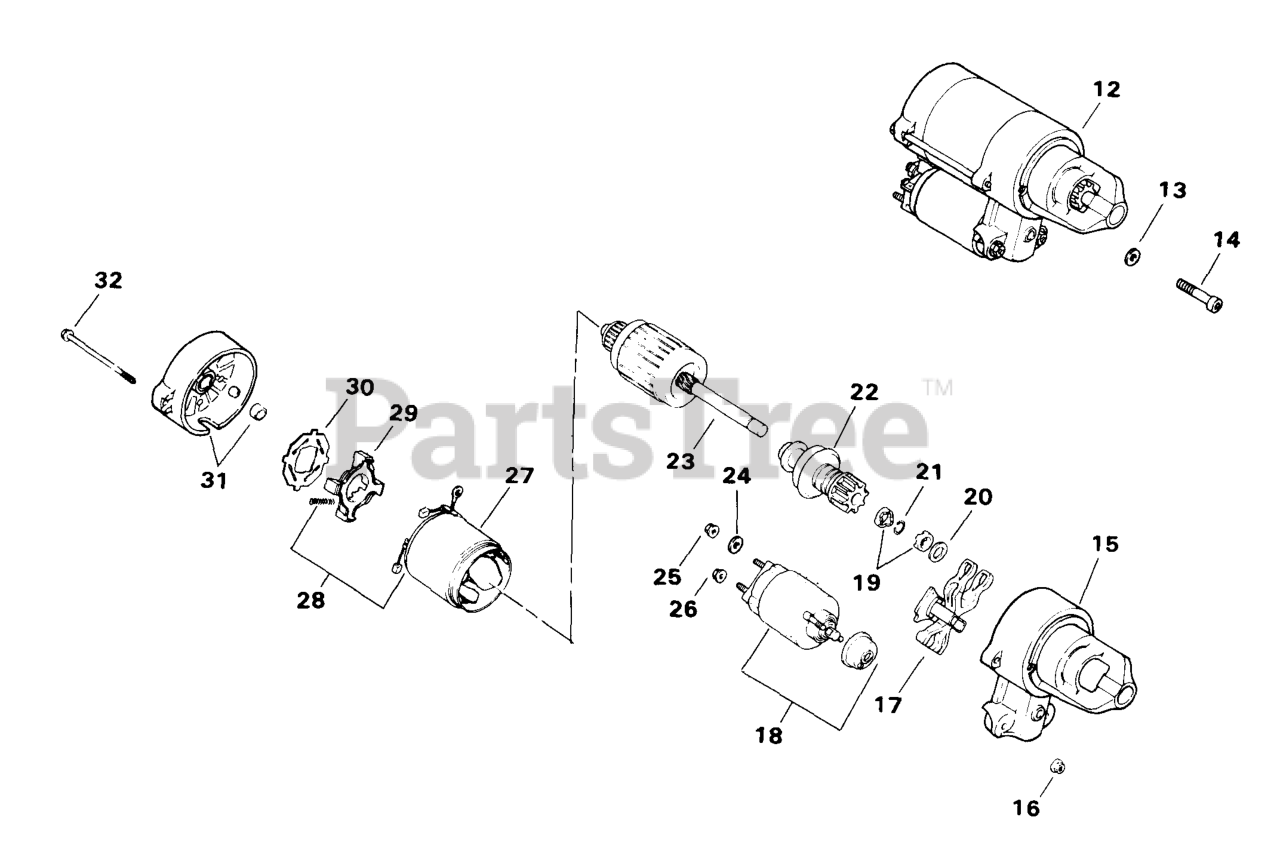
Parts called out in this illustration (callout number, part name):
12	ELEC STARTER-SOLENOID SHIFT-(#DSC)
13	WASHER, FLAT 1/4" (O.D. 1/2")
14	SCREW - (#DSC)
15	CAP, DRIVE END - DISCONTINUED
17	DRIVE LEVER
19	KIT - USE 24 755 84
20	KIT - USE 24 755 84
21	KIT - USE 24 755 84
22	DRIVE - (#DSC)
23	ARMATURE-DISCONTINUED
24	WASHER - DISCONTINUED
25	NUT - DISCONTINUED
28	BRUSH & SPRING KIT
29	BRUSH HOLDER
30	INSULATOR
31	CAP, COMMUTATOR END
32	THRU BOLT
2545003-S	TAG, CAUTION
